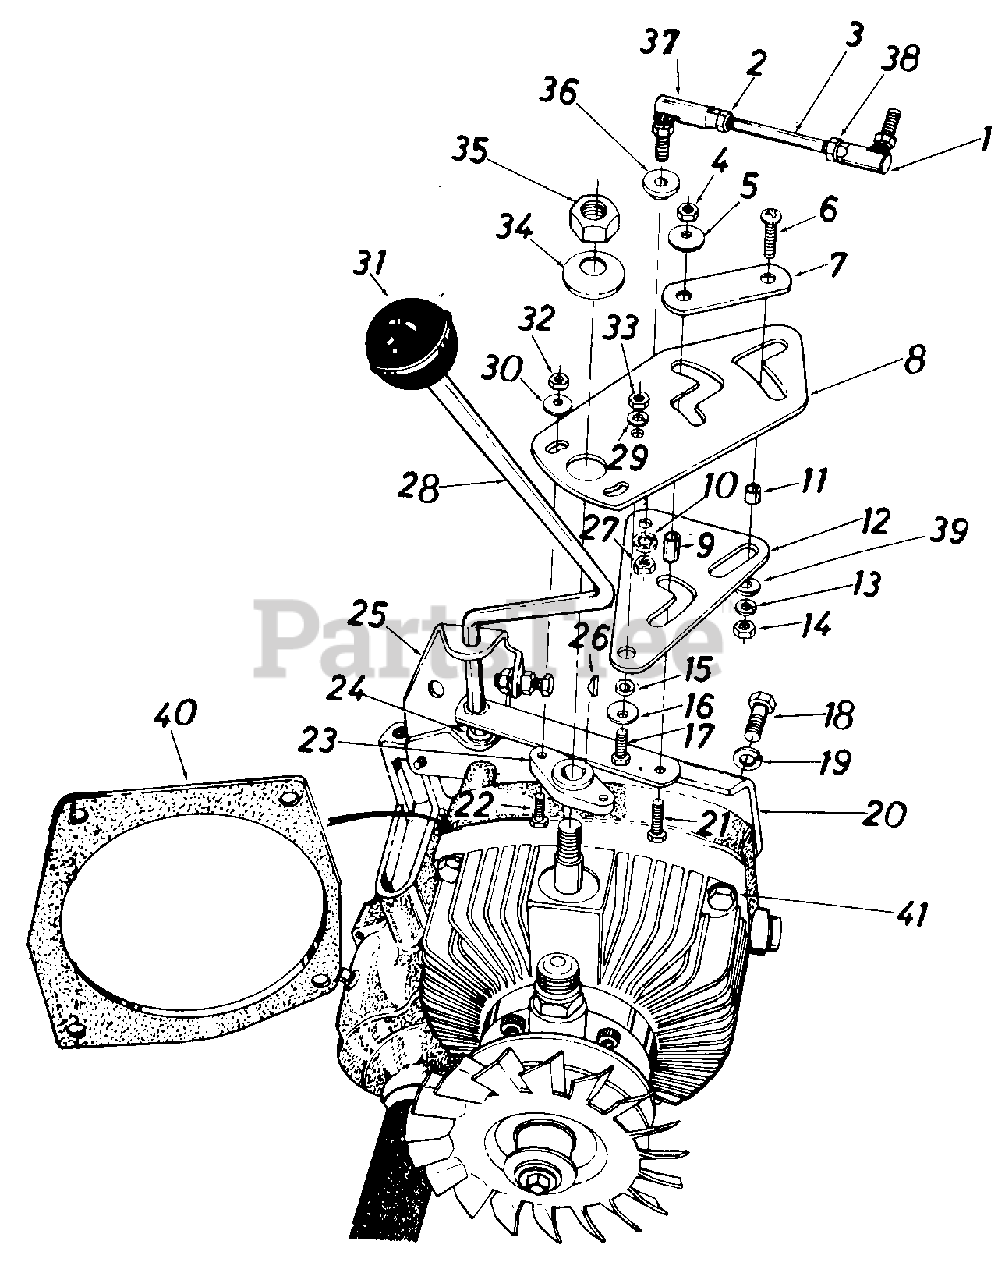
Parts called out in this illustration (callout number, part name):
1	Ball Joint Ass'y 3/8-24 Thd.
2	Hex Nut 3/8-24 Thd (L.H. Threads)
3	Control Rod 3/8-24 x 3 75" Lg
4	Hex Top L-Nut 3/8-24 Thd.
5	Fl-Wash. . 385" I .D. x . 87" O.D.
6	Truss Mach Scr. Phil 5/16-18 x 1 00" Lg.
7	Locking Link
8	Pintle Main Control Plate
9	Spacer .377" I D x .500" O.D. x 830" Lg
10	L-Wash 3/8" I.D.*
11	Spacer .315" I. D. x .500" O.D. x .350
12	Pintle Drive Plate
13	L-Wash 5/16" I D*
14	Hex Nut 5/16-18 Thd.*
15	Spacer .38" I.D. x .625"
16	Bell-Wash. .39" I D x 1.13" O.D.
17	Hex Bolt 3/8-24 x 100" Lg.*
18	Hex Bolt 3/8-1 6 x 10 " Lg. (Grade 5)
19	L-Wash. 3/8" I.D.*
20	Shift Lever Bracket
21	Hex Bolt 3/8-24 x 1.25" Lg.*
22	Hex Bolt 1/4-28 x .75" Lg.*
23	Pintle Hub
24	Nyliner .375" Dia. x .140
25	Shift Lever Bracket Upper
26	#5 Hi-Pro Key 1/8 x 5/8 Dia.
27	Hex Top L-Nut 3/8-24 Thd.
28	Shift Lever Ass'y
29	L-Wash. 3/8" I.D.*
30	Fl-Wash. . 385" I .D. x .87" O.D.
31	Gear Shift Knob
32	Hex Nut 1/4-28 Thd.
33	Hex Top L-Nut 3/8-24 Thd.
34	Bell-Wash. .505" I.D. x 1.00" O.D.
35	Hex Nut 1/2-13 Thd.*
36	Shld. Spacer .625" I.D.
37	Ball Joint Ass'y. 3/8-24 0 L.H.
38	Hex Jam Nut 3/8-24 Thd.
39	Fl-Wash. .33" I.D. x 1.25"
40	Gasket
41	Hex Bolt 2.75" Lg.
